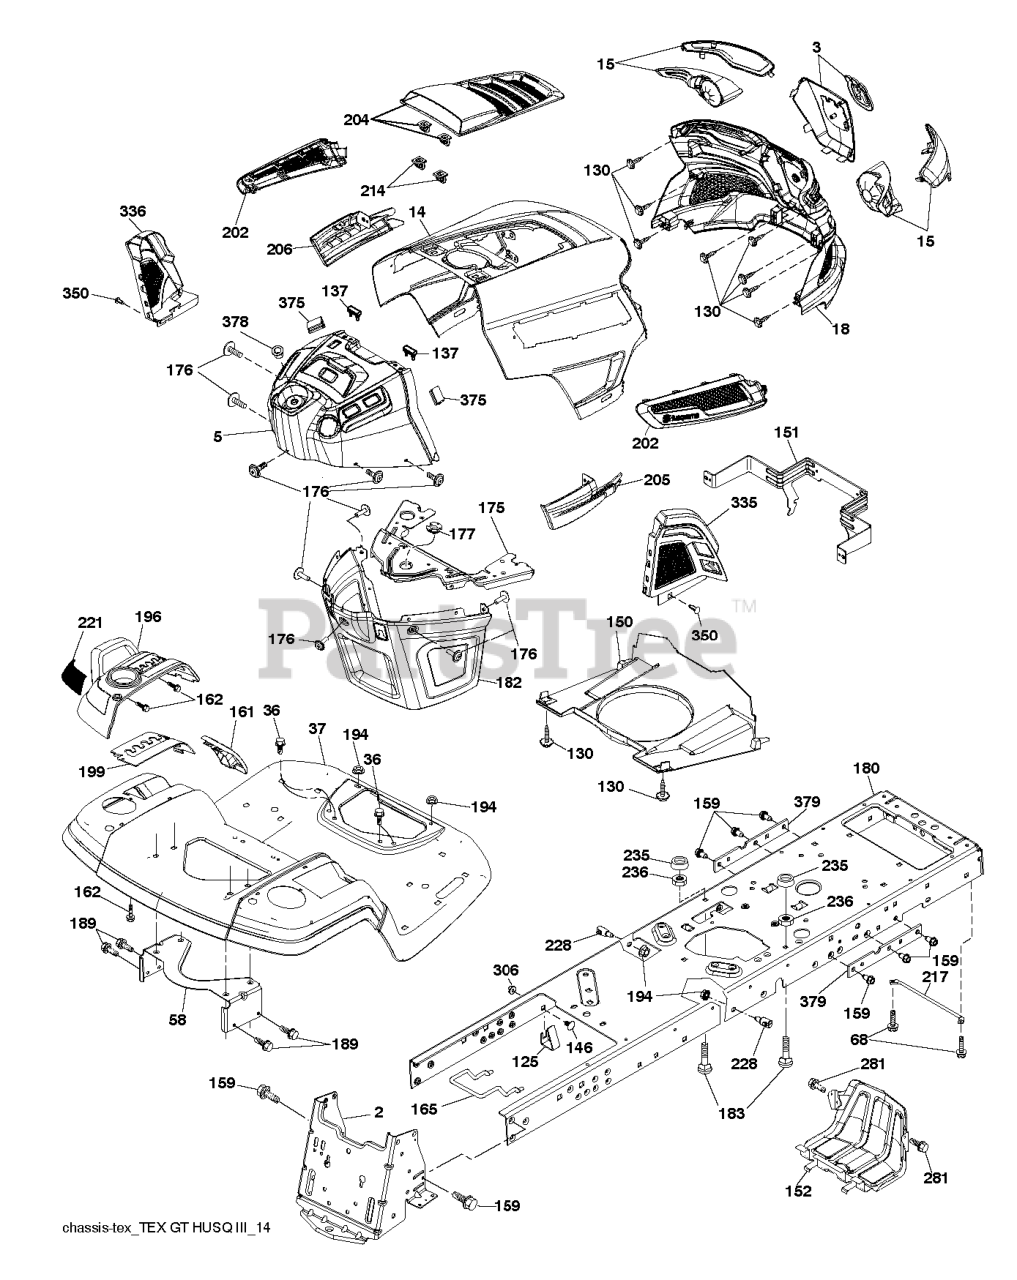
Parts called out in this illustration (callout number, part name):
2	DRAWBAR.STGT
14	HOOD.ASM.HUSQVARNA.GT.TEX.ORAN
15	Service Kit
36	SCREW 5/16"
37	FENDER.PNT.TX.GT.CH/FW/DL.HUSQ
58	BRKT.SUPPORT.FNDR/TANK
125	CLIP.FUEL.LINE
137	BUMPER DASH
146	BOLT.RDHD.SHT.SQNK.3/8-16X5/8
150	AIR.DUCT.GTV.BLACK
151	BRACKET.PIVOT.HOOD.GT.HUSQ.II
152	SHIELD.BROWNING.PNT.GT.V2
159	SCREW, 3/8-16X3/4
161	CONSOLE.WINDOW.FUEL.HUSQ.GT
165	SUPPORT.TANK.REAR.B/TE
175	PLATE.PNT.CROSSMEMBER.HUSQ/PRE
176	SCREW.#10-24X5/8.RN.QU
177	BUSHING STEERING
180	CHASSIS.LT/GT.BOLTED
182	DASH.LOWER.COMMON.12V.ADAPTOR
189	SCREW
196	SUBASM.CONSOLE.HUSQ.GT.DECKLFT
199	PLATE.DECK.LIFT.HUSQVARNA.GT
202	Vents
204	Vents
205	SIDE.TRIM.RH.GT.HUSQ.II
206	SIDE.TRIM.LH.GT.HUSQ.II.GRAY
214	CLIP.RETAINER.TINNER.
217	ROD.PIVOT.HOOD
221	REFLECTOR.LH.TEX GT HU
228	STUD.W/"D"ANTI-ROTATION
236	NUT.CENTERLOCK.5/16-
281	SCREW 3/8-16X1
306	NUT LOCK FLG 3/8-16 UNC
335	COVER.LOWER.DASH.RH.BLACK
336	COVER-LH.LOWER.DASH.GT2.BLACK
350	CLIP.X-MAS.TREE
375	BUMPER CLIP-ON. DASH 1"
378	BUSHING FLANGE; PLASTIC
379	CHASSIS.PLATE.REINFORCEMNT.431
